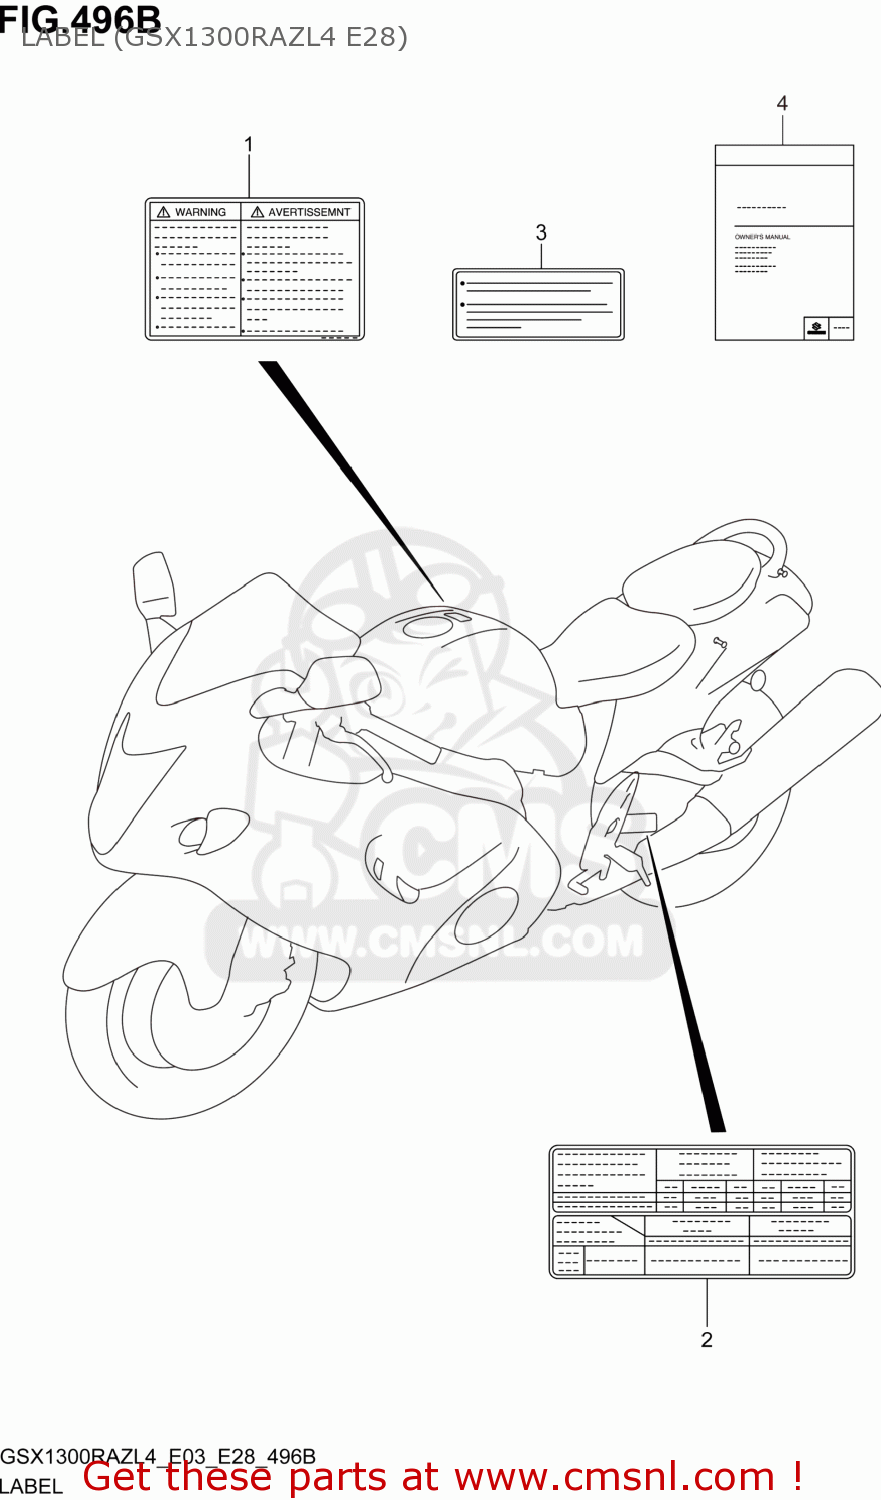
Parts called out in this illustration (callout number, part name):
1	LABEL,GENERAL WARNING
2	LABEL,TIRE INFORMATION
3	LABEL,FUEL INFORMATION
4	MANUAL,OWNER'S
